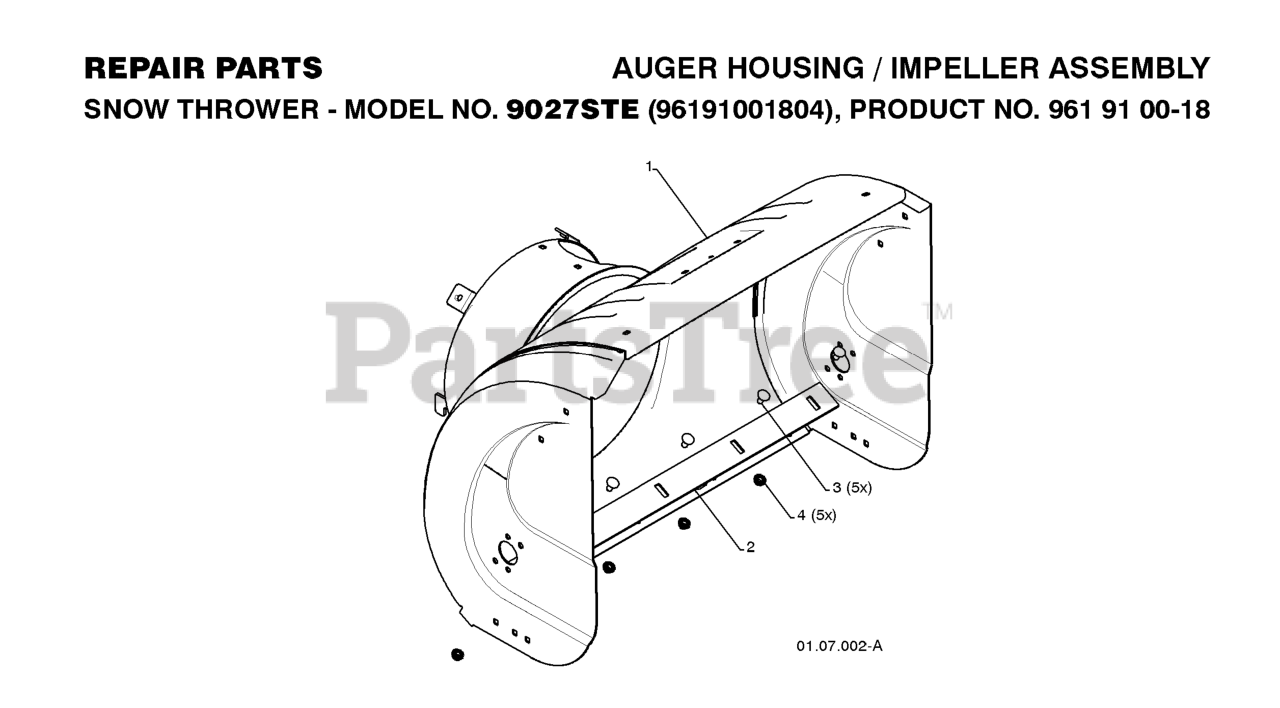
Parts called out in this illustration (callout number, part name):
1	HOUSING, AUGER
2	BAR, SCRAPER
3	BOLT
4	NUT.FLANGE.5/16
